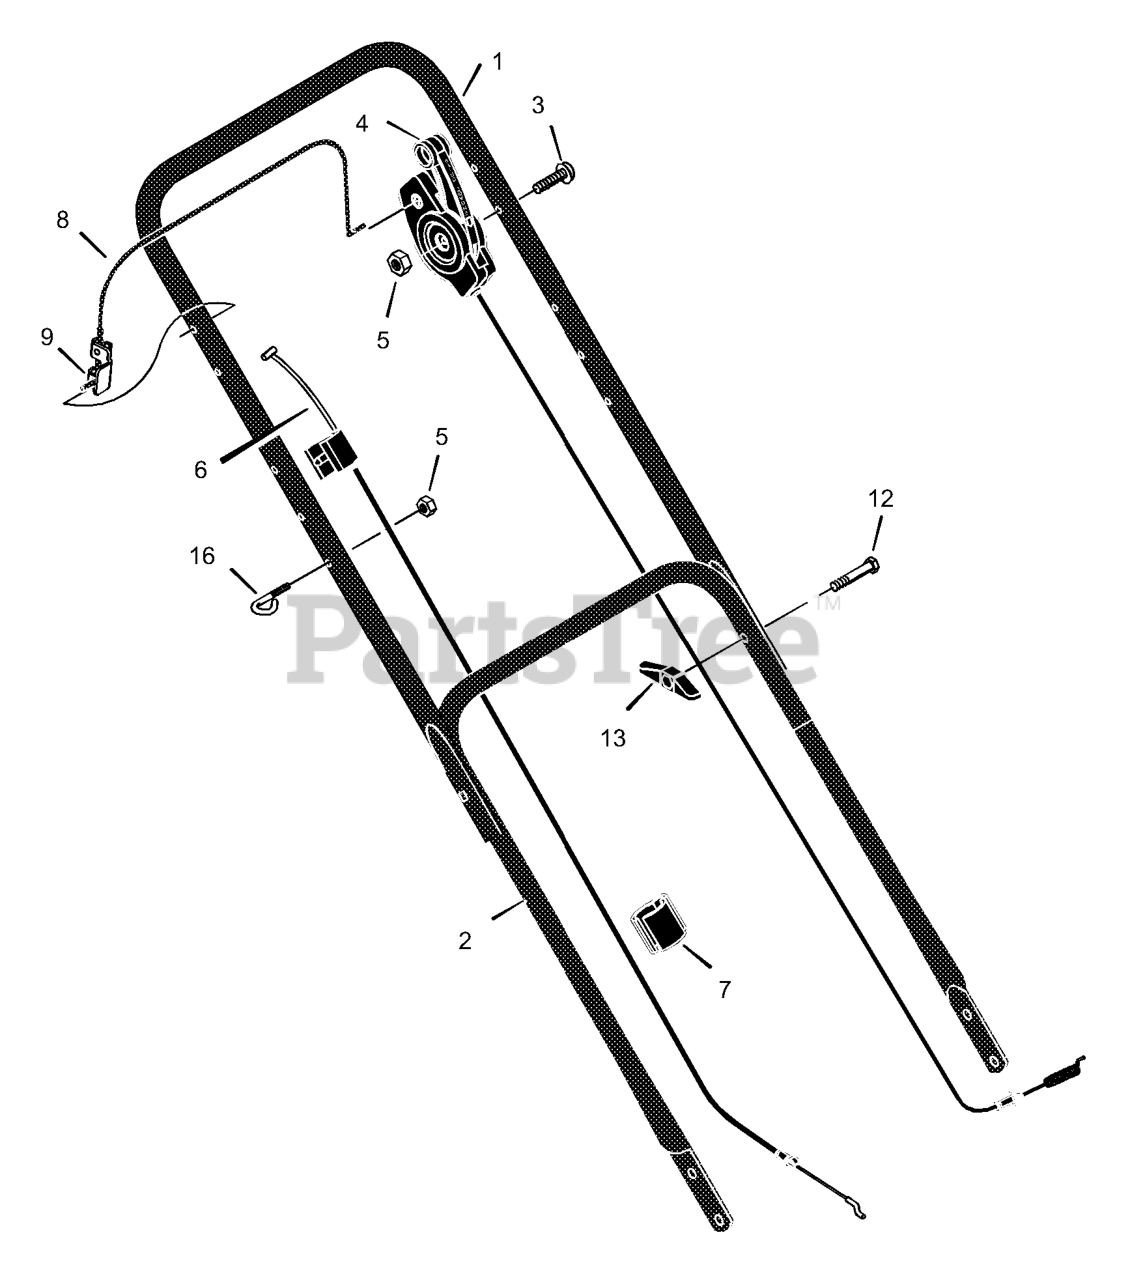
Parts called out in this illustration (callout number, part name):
1	Handle, Upper (Black)
2	Handle, Lower (Black)
4	Control, Drive
5	Locknut
6	Cable, Stop
7	Fastener, Double Cable
7	Throttle Control
8	Lever, Stop
9	Bracket, Stop Lever
13	Knob
16	Guide, Rope
